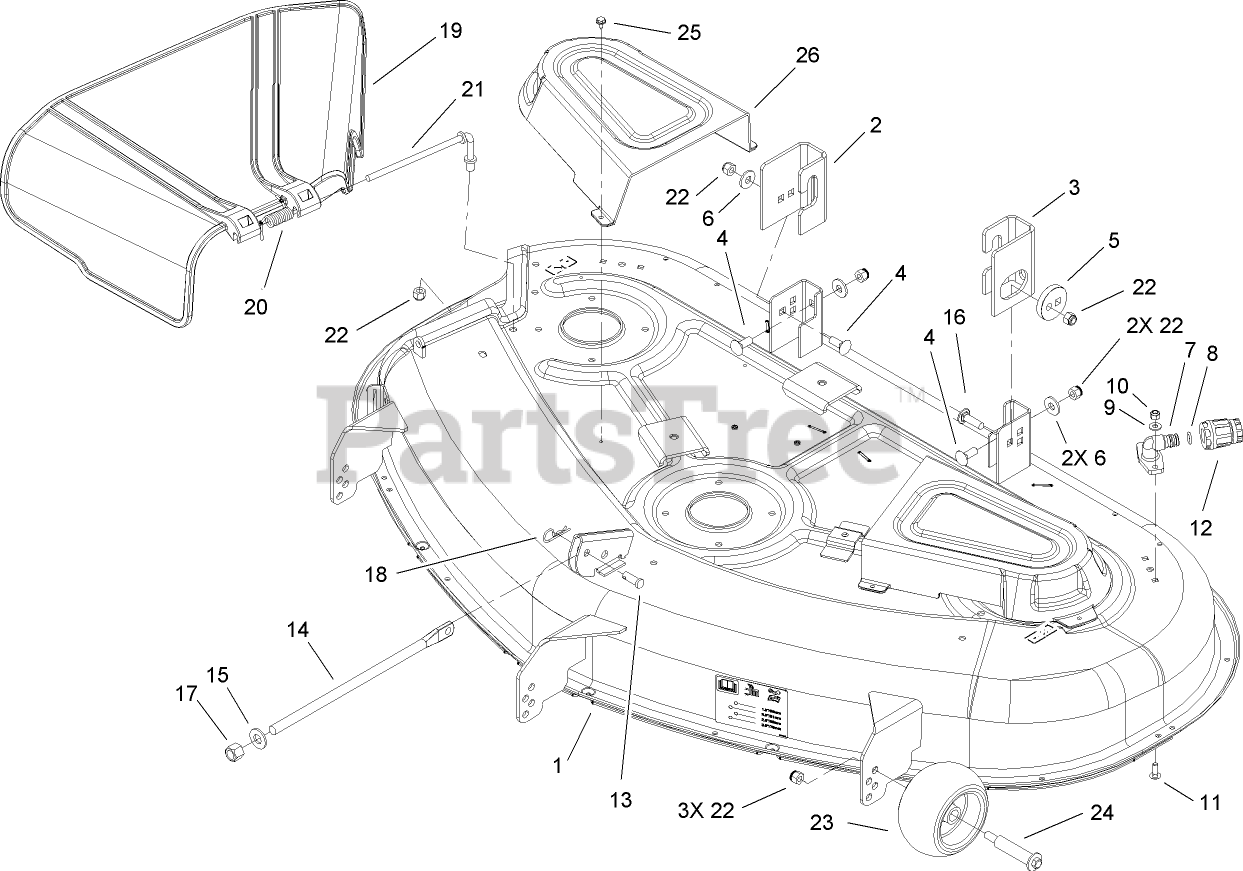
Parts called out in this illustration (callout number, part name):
2	BRACKET-HANGER, RIGHT REAR
3	BRACKET-HANGER, LEFT REAR
4	BOLT-CARR
5	ECCENTRIC
6	WASHER-HARDENED
8	O-RING
9	WASHER-FLAT
10	NUT-LOCK, NI
11	BOLT-CARR
12	CONNECTOR-HOSE
13	PIN-CLEVIS
14	ROD-LIFT
15	WASHER-THRUST
16	SCREW-CARR
17	NUT-LOCK, NI
18	PIN-HAIR
19	DEFLECTOR
20	SPRING-TORSION
21	ROD-PIVOT
22	NUT-LOCK, NI
23	ROLLER-SCALP, ANTI
24	BOLT-SHOULDER
25	SCREW-HWHTF
26	COVER-BELT
